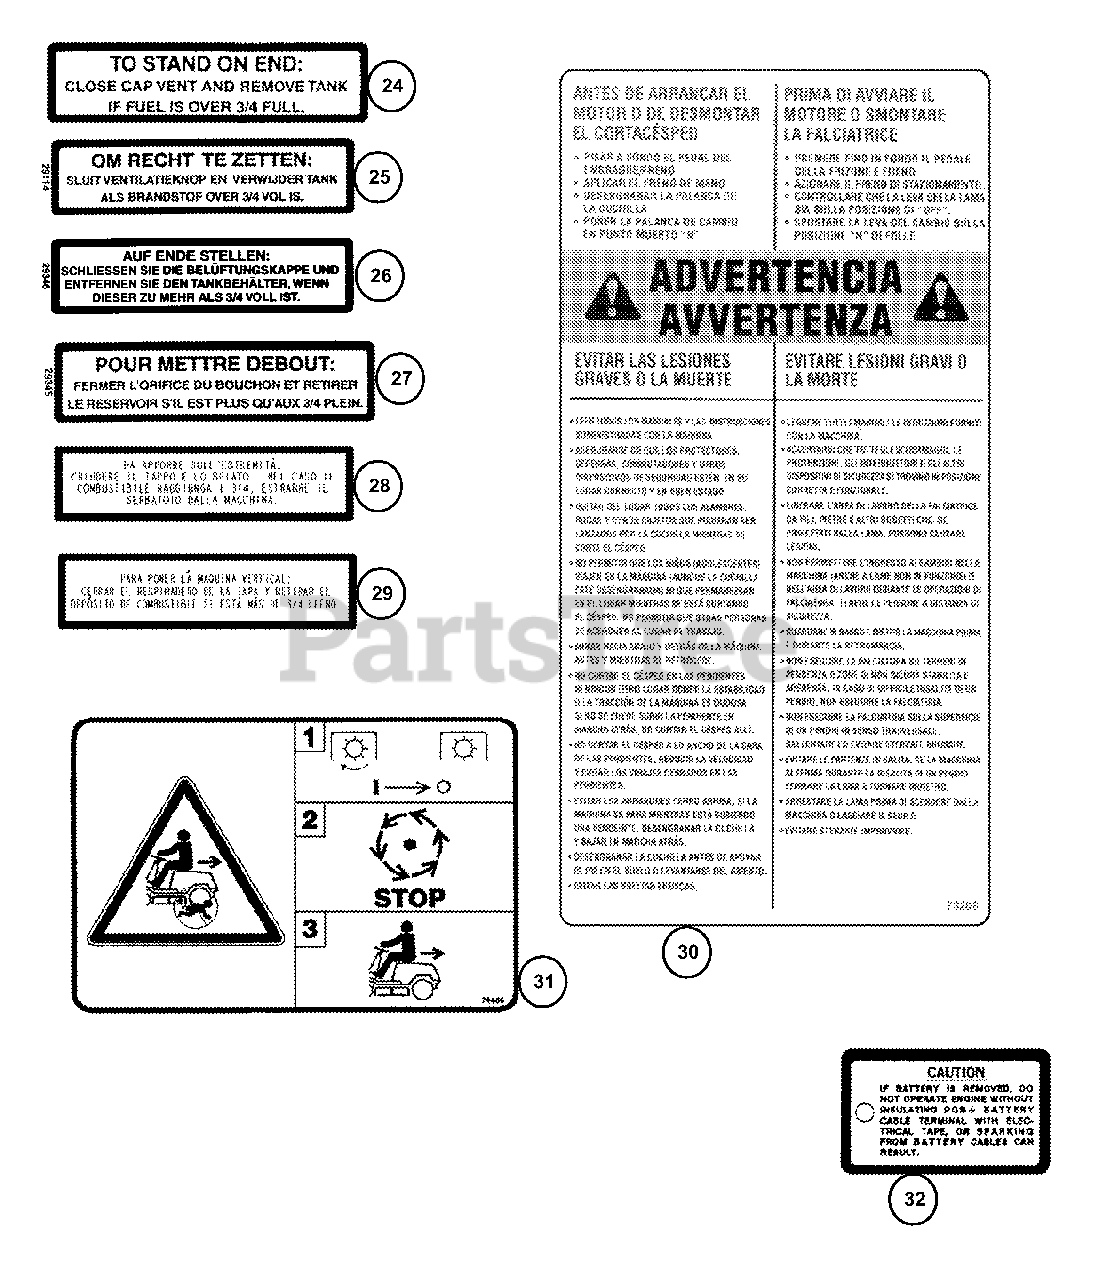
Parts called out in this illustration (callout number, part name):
24	DECAL, CAUTION, Fuel
25	DECAL, CAUTION, Fuel Leakage (Dutch)
26	DECAL, CAUTION, Fuel Leakage (German)
27	DECAL, CAUTION, Fuel Leakage (French)
28	DECAL, CAUTION, Fuel Leakage (Italian)
29	DECAL, CAUTION, Fuel Leakage (Spanish)
30	DECAL, Safety Instructions (Spanish/Italian)
31	DECAL, No Mow in Reverse
32	TAG, Caution
